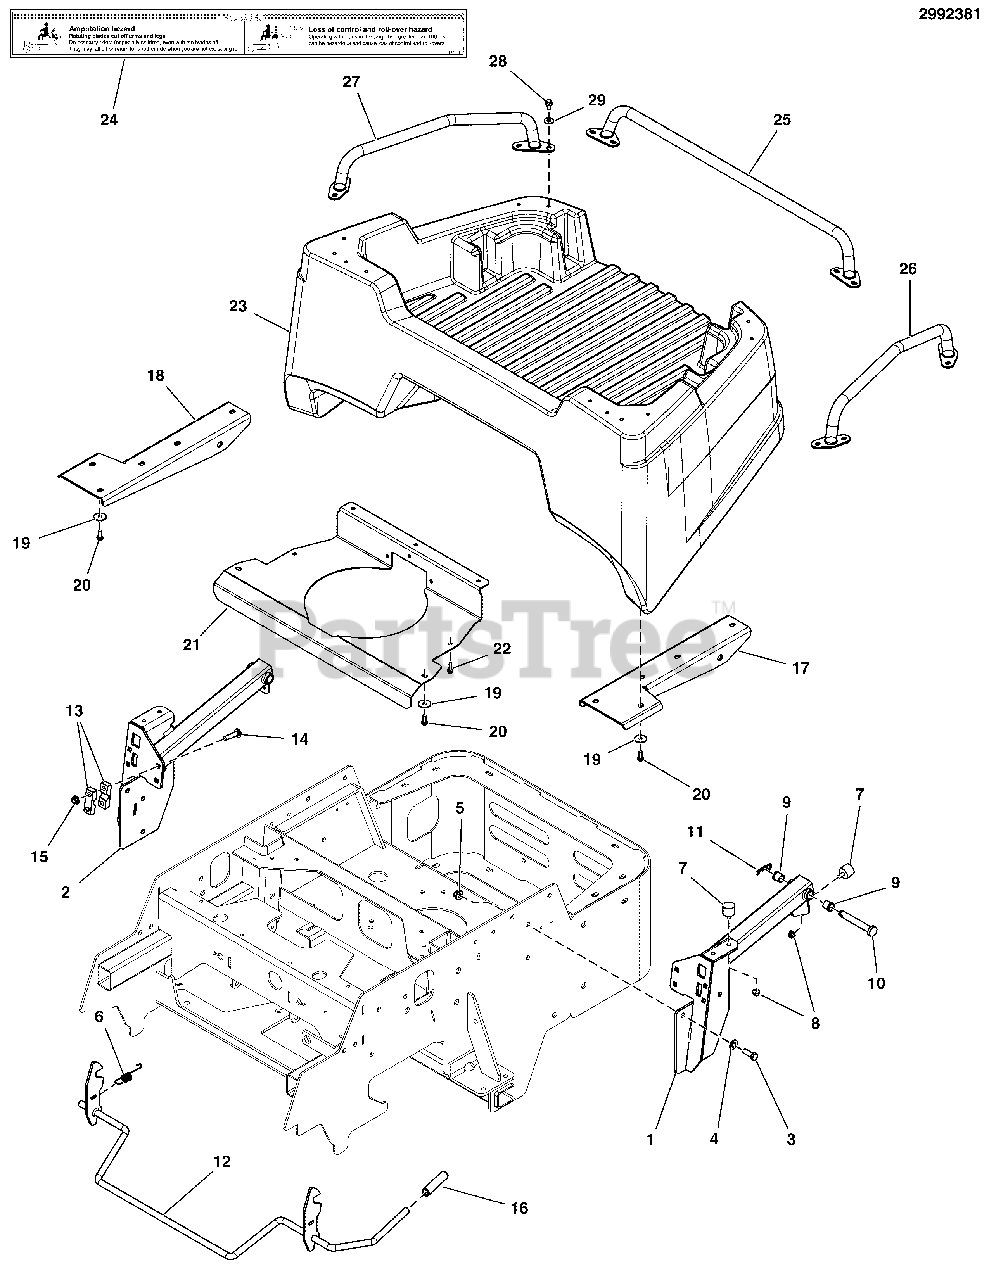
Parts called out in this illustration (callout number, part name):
1	WELDMENT, CARGO BOX SUPPORT-LH (BLACK)
2	WELDMENT, CARGO BOX SUPPORT-RH (BLACK)
3	BOLT, 3/8-16 X 1 GD5 CZ
4	WASHER, 3/8 SAE
5	NUT, 3/8-16 HEX NYLOCK FLANGE
6	SPRING, EXTENSION
7	BUMPER, RUBBER 1/4-20
8	NUT, 1/4-20 HEX SERR. FLANGE
9	BUSHING-0.505IDX0.63 ODX0.62 LG NY/GLASS
10	PIN, CLEVIS, 1/2 X 3-1/2
11	PIN, 3/32 X 1.600, HAIR, ZINC/CLEAR
12	WELDMENT, CARGO BOX LATCH (BLACK)
13	BEARING, HALF - .267 RAD (NYLON)
14	BOLT,5/16-18X1.500,CARRIAGE,SQ,GR5,ZC/CL
15	NUT,5/16-18,HEX FLNG,CNTR LCK,ZC/CL
16	GRIP, FOAM, .475 X 3.00 X .095
17	BRACKET, CARGO BED MOUNT (LH)(BLACK)
18	BRACKET, CARGO BED MOUNT (RH)(BLACK)
19	WASHER, 1/4 FENDER
20	HHCS, 1/4-20 X 0.625, GR5, ZINC/CLEAR
21	PLENUM, CARGO - 560Z/CONT BRIGGS (BLACK)
22	SCREW, HEX WASHER HD - SELF PIERCING
23	BOX, CARGO - 560Z/CONTENDER
24	DECAL, 560Z CARGO BED DECAL
25	WELDMENT, FRONT RAIL - CARGO (560Z/CONT)
26	WELDMENT, LH RAIL - CARGO (560Z/CONT)
27	WELDMENT, RH RAIL - CARGO (560Z/CONT)
28	SCREW,1/4-20X0.500 HEX WZ LOCK FLG CL/ZN
29	FW, .281X.75X.051
